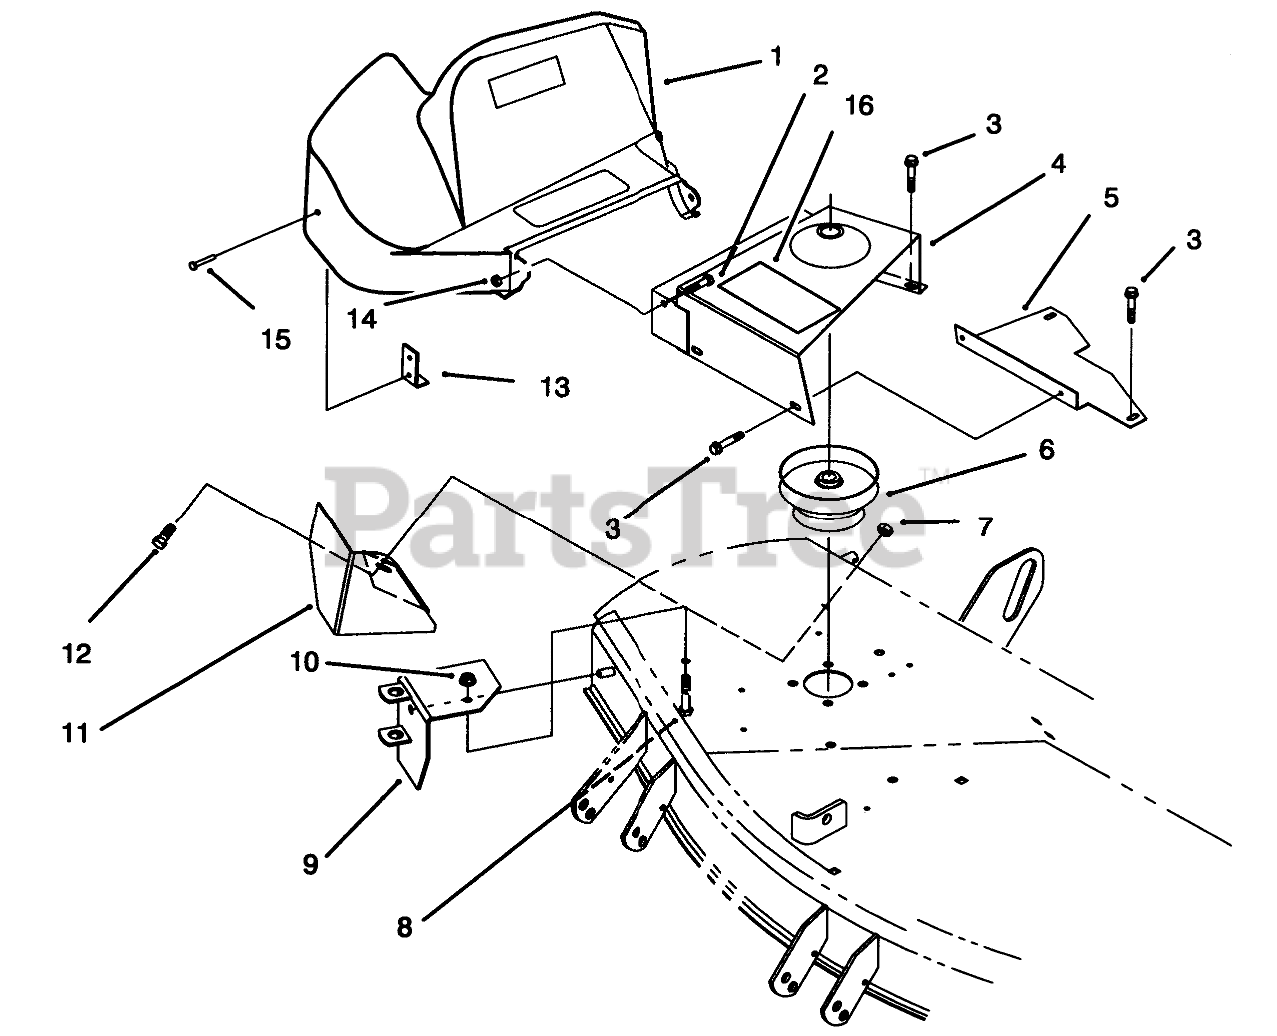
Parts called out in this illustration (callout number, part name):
1	SHIELD-BELT
2	SCREW-HH
3	Bolt
4	42" Inner Shield Assembly (Incl. Ref. #16)
5	42" ADAPTOR SHIELD B
6	PULLEY
7	NUT-LOCK, NI
8	SCREW-HH
9	PIVOT SUPPORT ASM
10	NUT-HF
11	42" DEFLECTOR B
12	SCREW-CARR
13	BRACKET-SUPPORT, SHIELD
14	NUT-LOCK, NI
15	RIVET-POP
16	DECAL-DANGER
